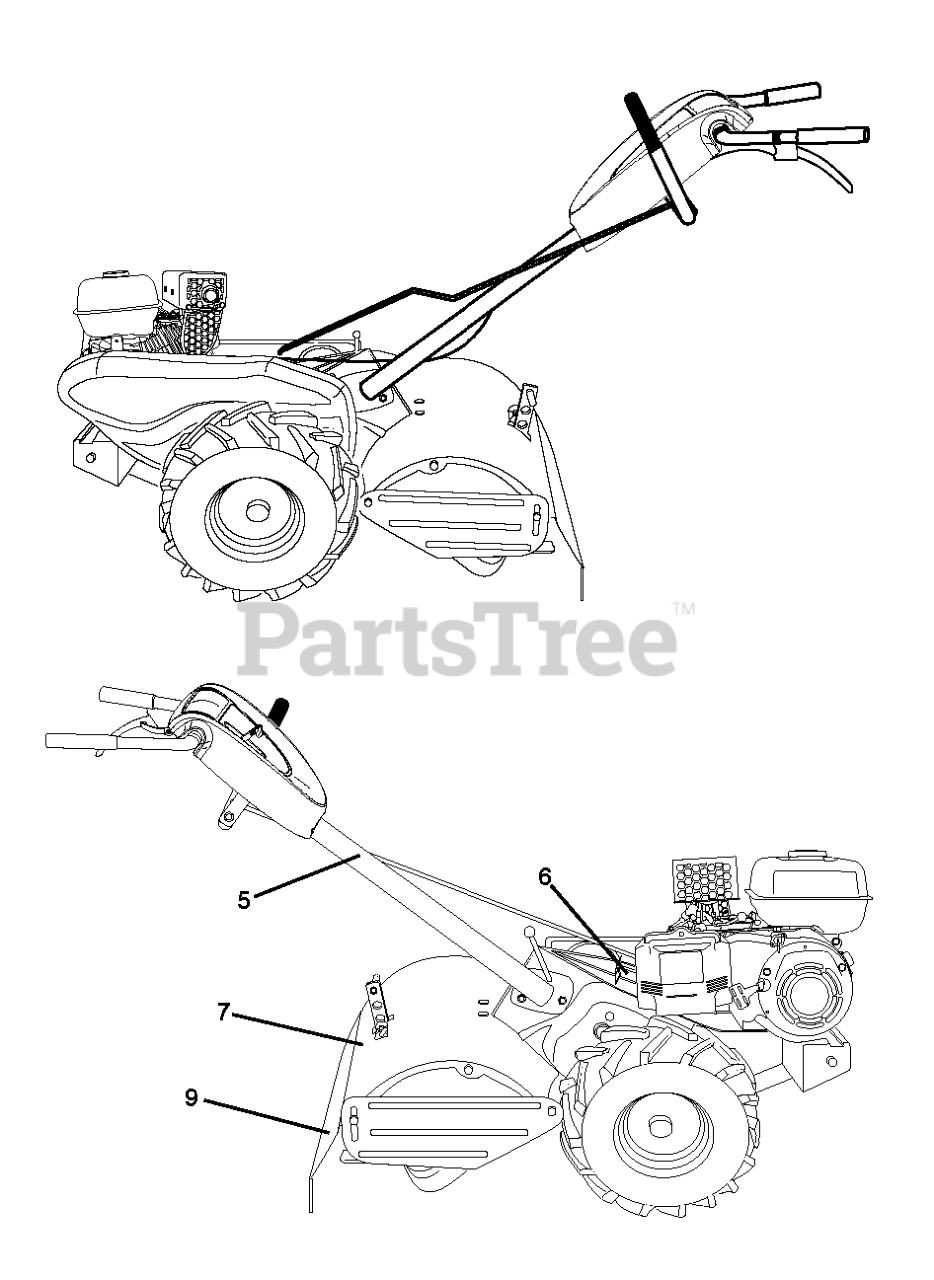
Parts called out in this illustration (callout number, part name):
5	DECAL TI (2 2)
6	DECAL.SHIFT.INDICATOR.TILLER
7	DECAL.WARNING.SHLD.ENG/FR
9	DECAL TI
